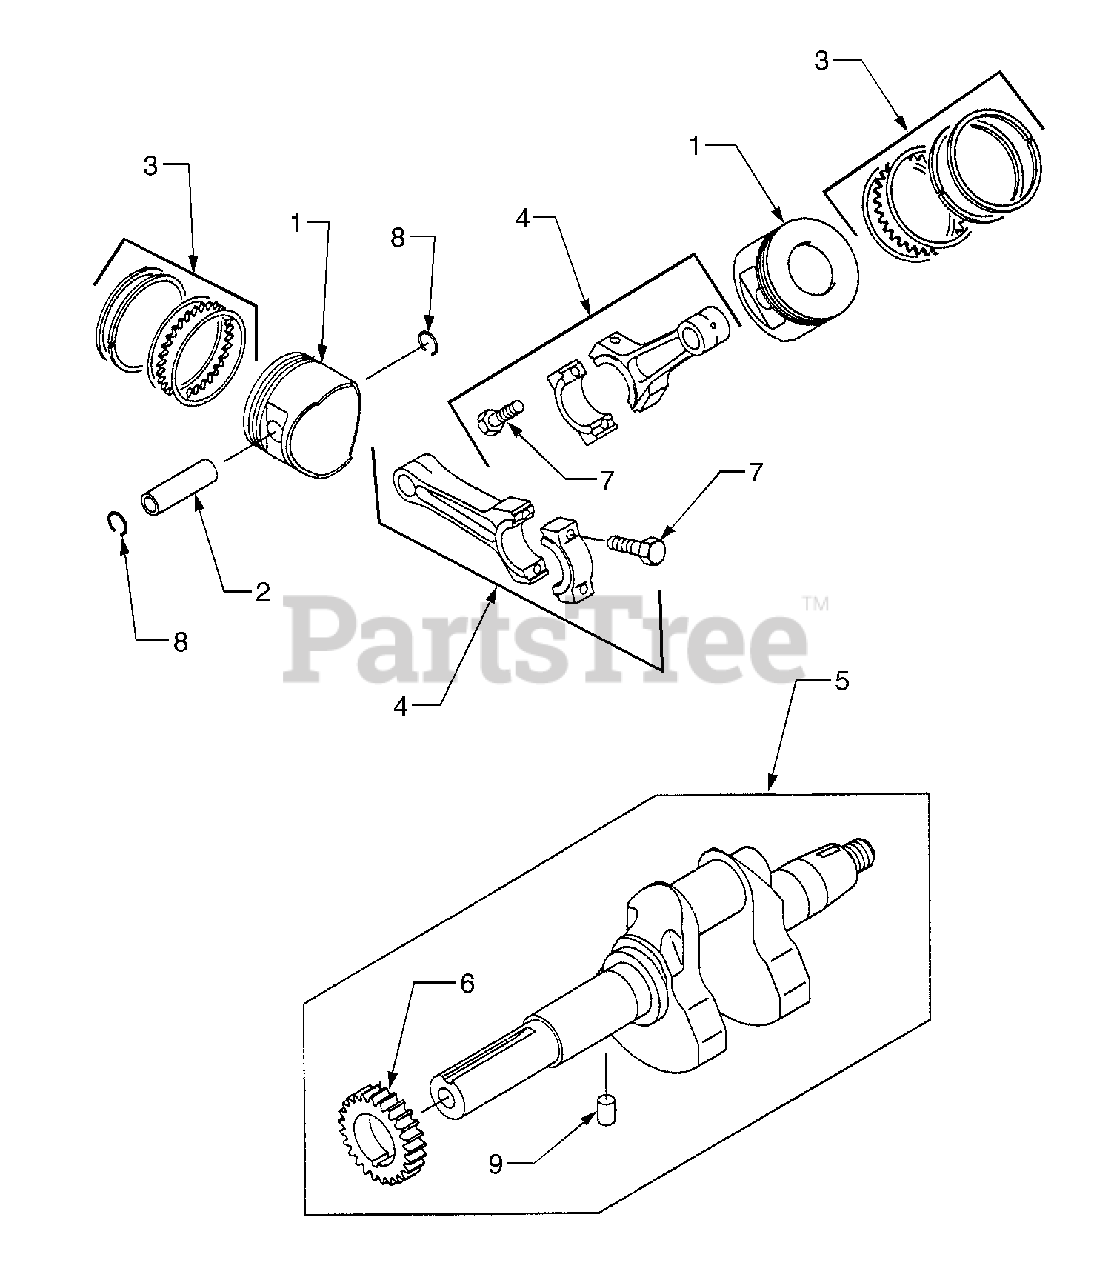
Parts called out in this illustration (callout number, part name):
3	Ring Set, Std.
4	Rod Assembly, Connecting
7	Bolt, Connecting Rod
8	Retaining Ring, Piston Pin
